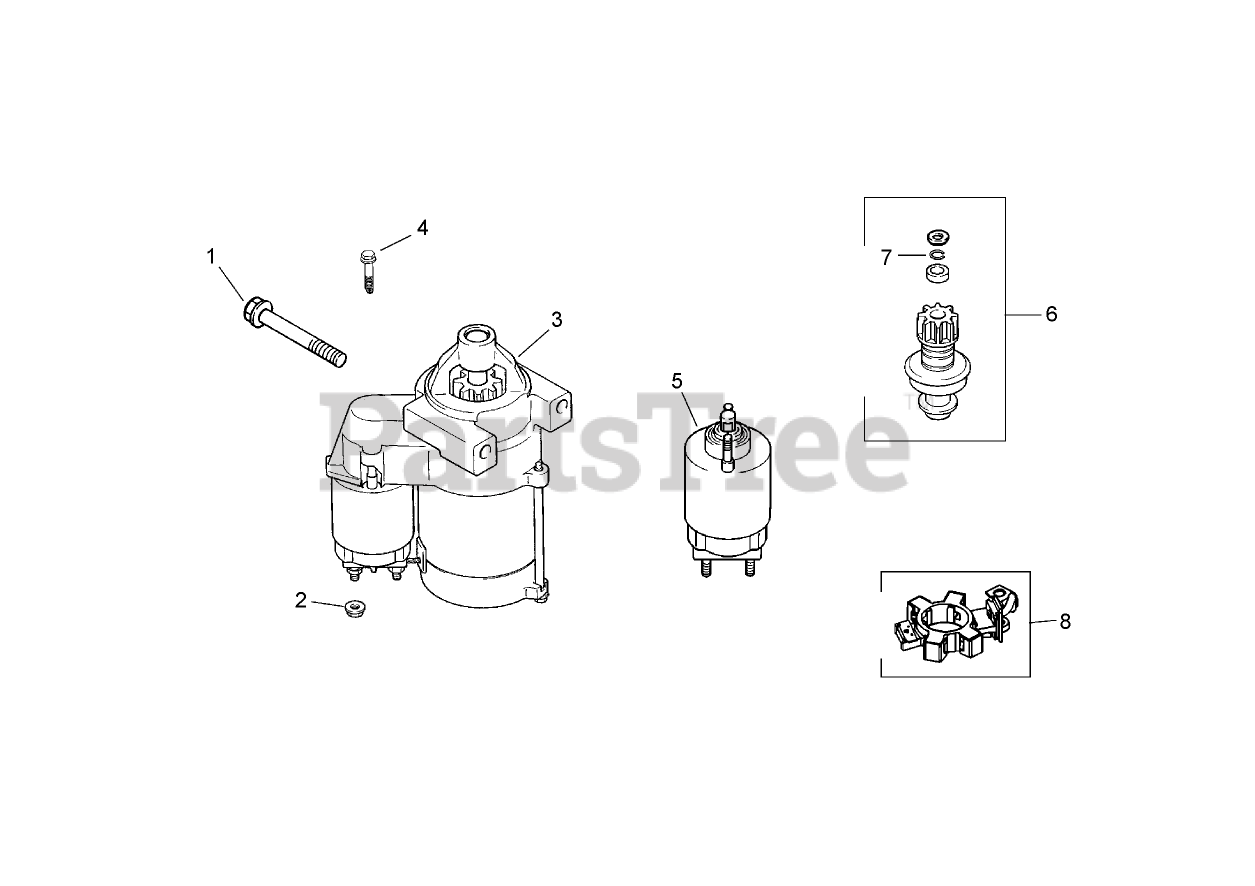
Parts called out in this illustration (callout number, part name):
1	SCREW-FLG (M8X1.25X80)
2	NUT-FLANGE (M8X1.25)
3	Starter ASM (Incl. Ref. No. 4-8)
4	SCREW-TORX HEAD, EXTERNAL
5	Solenoid Kit (Incl. Ref. No. 4)
6	Pinion Drive Kit (Incl. Ref. No. 7)
7	RING-RETAINING
8	BRUSH HOLDER KIT
